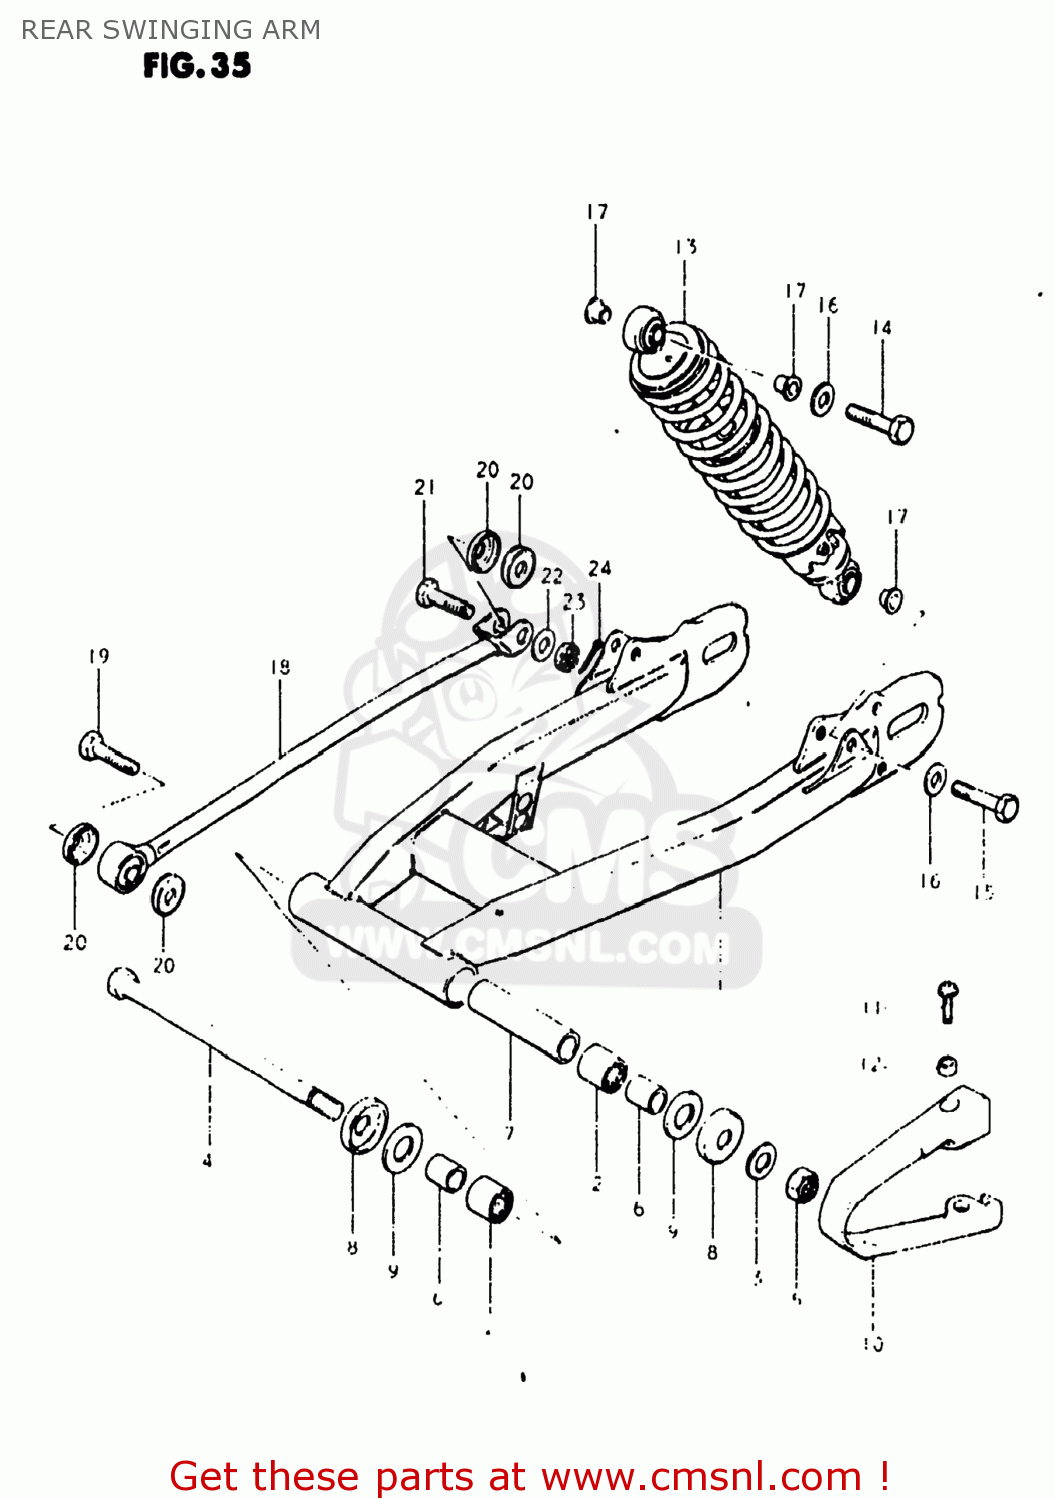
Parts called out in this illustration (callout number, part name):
1	SWING ARM ASSEMBLY,REAR
2	BEARING(22X29X20)
3	WASHER
4	SHAFT,REAR SWING ARM
5	NUT 16MM
6	SPACER,RR SWGARM PIVOT
7	SPACER (16.2X21.7X142)
8	COVER,RR SWGARM DUST SEAL
9	WASHER
10	BUFFER,CHAIN TOUCH DEFLECTOR
11	SCREW,CHAIN TOUCH DEFEND
12	SPACER (5.5X8X4)
13	ABSORBER ASSEMBLY,REAR SHOCK
14	BOLT
15	BOLT
16	WASHER
17	SPACER,RR SHK ABS INNER
18	TORQUE LINK,REAR
19	BOLT(8X25)
20	21
21	BOLT 8X28
22	WASHER
23	NUT 8MM
24	PIN 20X20
